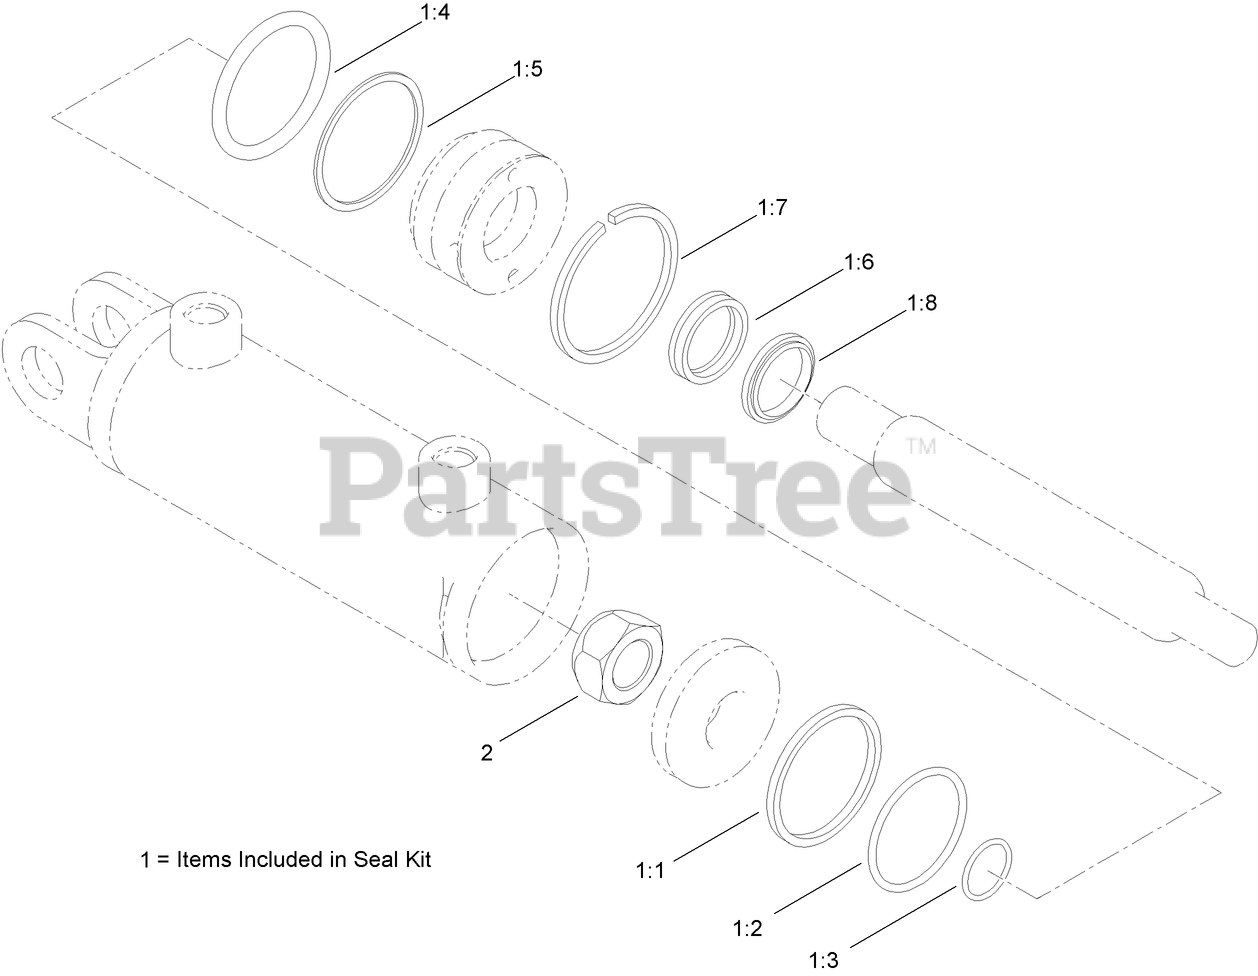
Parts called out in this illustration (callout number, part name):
1	SEAL KIT
1:1	Seal-Teflon
1:2	O-RING
1:3	O-RING
1:4	O-RING
1:5	Washer-Back Up
1:6	Seal-U Cup
1:7	RING-RETAINING
1:8	WIPER
2	NUT-LOCK
